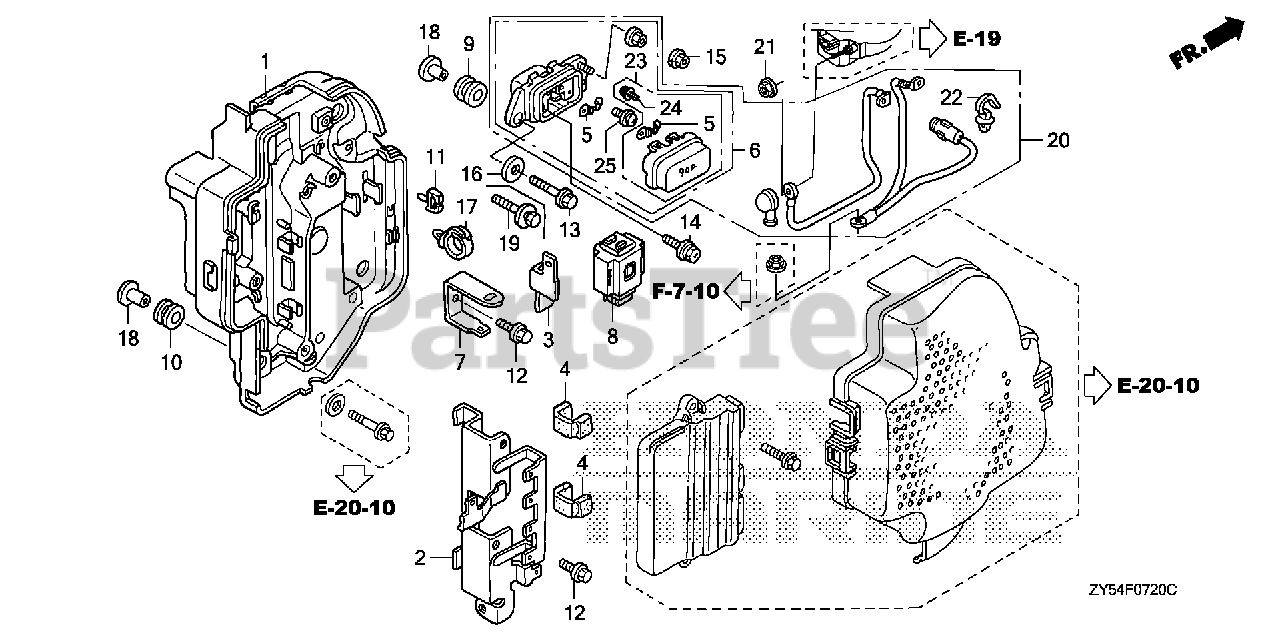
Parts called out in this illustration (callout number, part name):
1	CASE, ELECTRONIC PARTS
2	BRACKET B, CONNECTOR
3	BRACKET C, CONNECTOR
4	SUSPENSION, ECU UNIT
5	FUSE (90A)
6	BOX ASSY., FUSE (90A)
7	BRACKET, FUSE BOX
8	RELAY ASSY., AIR FUEL SENSOR
9	GROMMET, RELAY
10	GROMMET, CASE (LOWER)
11	E-CLIP, WIRE HARNESS
12	BOLT, FLANGE (6X10)
13	BOLT, FLANGE (6X25)
14	BOLT-WASHER (6X16)
15	NUT-WASHER (6MM)
16	WASHER, PLAIN (6MM)
17	CLIP, WIRE HARNESS
18	COLLAR, MODULE IGNITION CONTROL CASE (CDI)
19	BOLT-WASHER (6X25)
20	CABLE ASSY., ALTERNATOR FUSE
21	NUT-WASHER (6MM)
22	CLIP, HARNESS BAND (145MM) (BLACK)
23	COVER ASSY., FUSE (90A)
24	SCREW-WASHER (3X7)
25	SCREW-WASHER (5X12)
